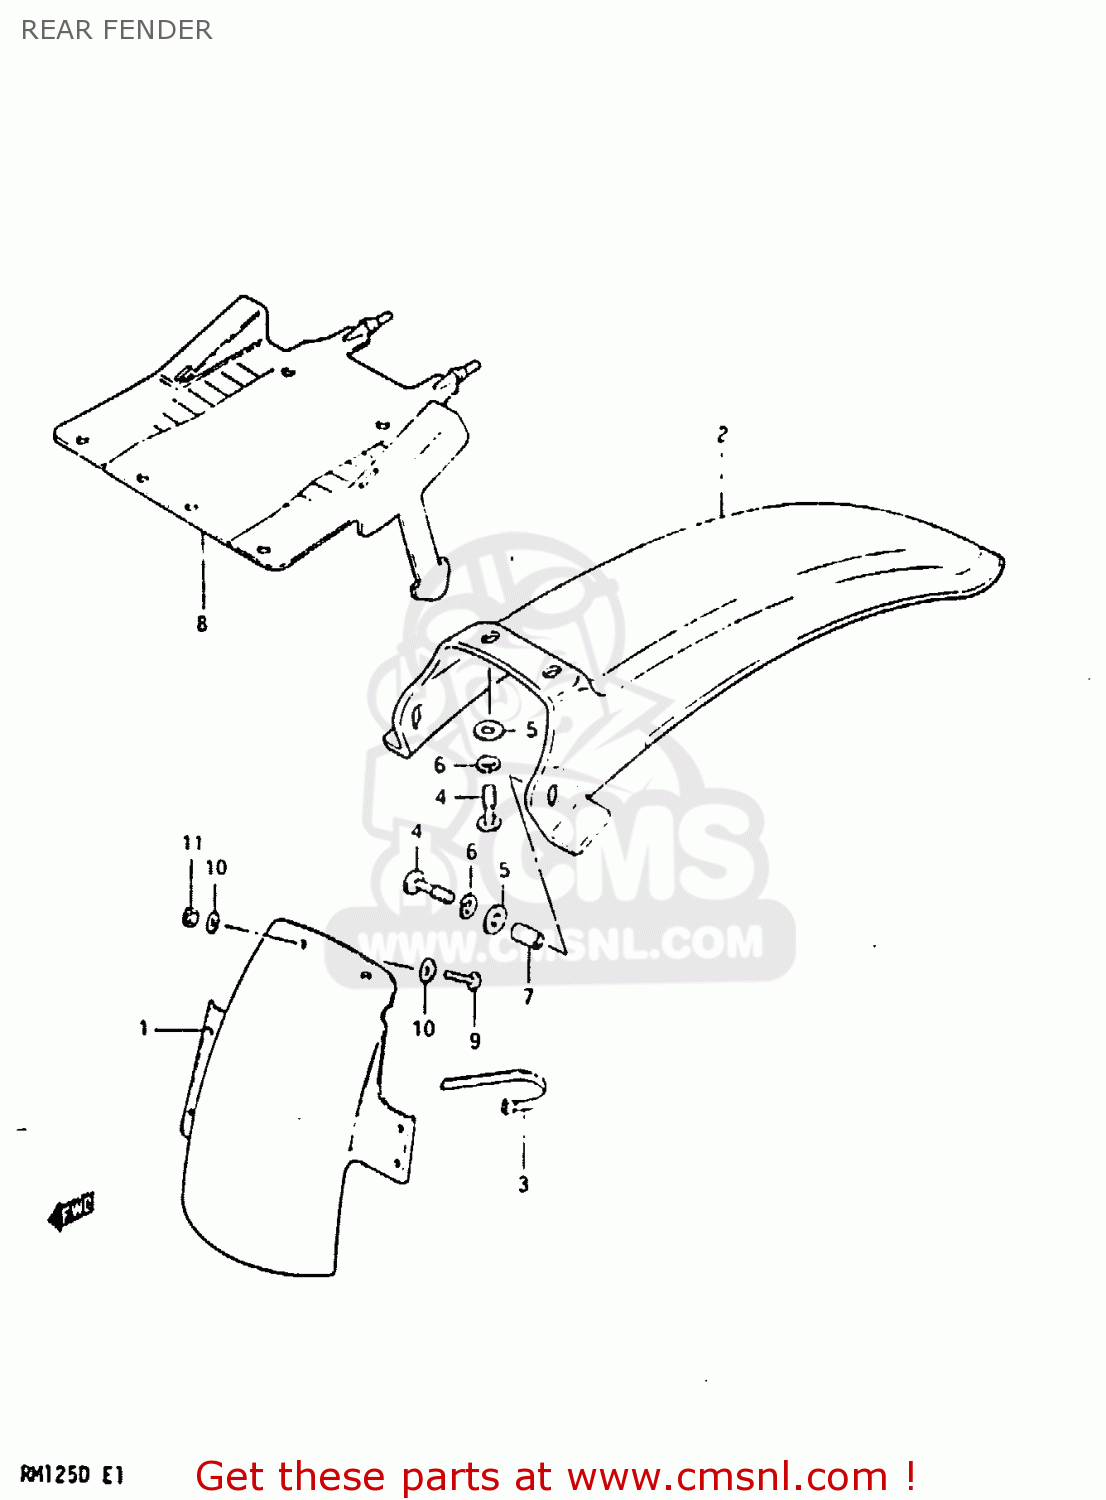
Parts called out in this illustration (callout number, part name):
1	REAR FENDER,FRONT
2	FENDER,REAR
3	CLAMP
4	SCREW
5	WASHER (6.5X20X1.2)
6	LOCK WASHER
7	SPACER
8	GUIDE,RR FENDER MUD
9	SCREW
11	WASHER
12	NUT
